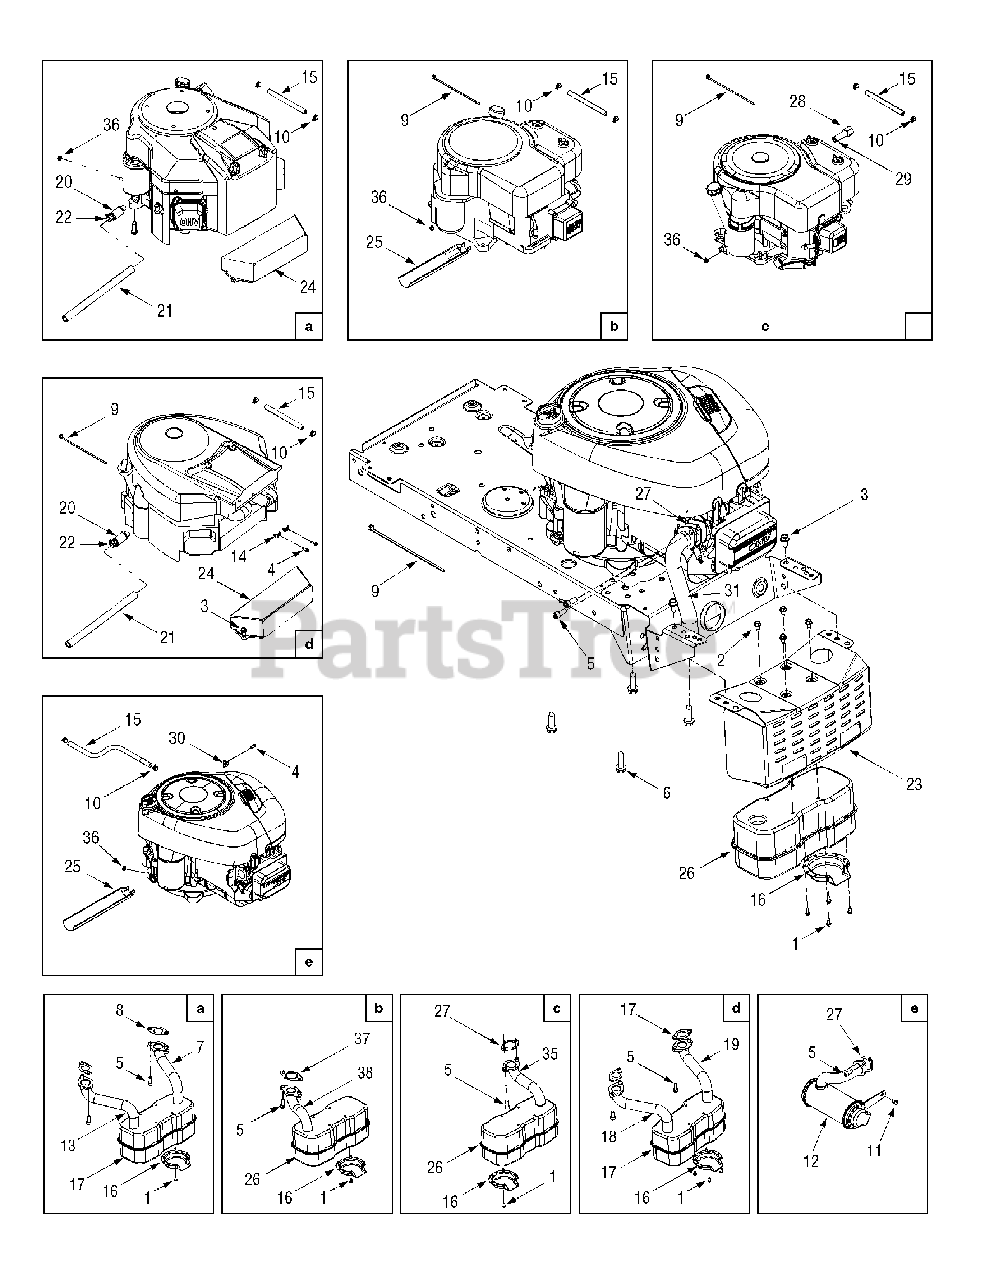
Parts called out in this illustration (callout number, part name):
1	Screw, #8-32, .375
2	Self-tapping Screw, 1/4-14, .625
3	Self-tapping Screw, 5/16-12, .75
4	Screw, #10-32, .625
5	Socket Cap Screw, 5/16-18, .625
6	Self-tapping Screw, 3/8-16, 1.25
7	LH Exhaust Pipe
8	Exhaust Gasket
9	Cable Tie, 7.4"
10	Hose Clamp, .490
11	Screw, 1/4-20, 0.500
12	Muffler, Exhaust
13	RH Exhaust Pipe
14	Casing Clamp
15	Fuel Line Hose
16	Muffler Deflector
17	Muffler, Twin Inlet
18	RH Exhaust Pipe
19	LH Exhaust Pipe
20	Oil Drain Valve
21	Oil Drain Hose
22	Oil Drain Cap
23	Muffler Heat Shield
24	Engine Heat Shield
25	Oil Drain Sleeve
26	Muffer, Single Inlet
27	Exhaust Gasket
28	Oil Drain Cap, 3/8-18
29	Oil Drain Pipe, 3/8-16, 2.0
30	Casing Clamp
31	Exhaust Pipe
32	Screw, #8-18 x .50
33	Hex Screw, 7/16-20, 1.25
34	Belt Keeper Pin, 5/16, 4.75
35	Exhaust Pipe
36	Hex Sems Nut, 1/4-20
37	Exhaust Gasket
38	Exhaust Pipe
